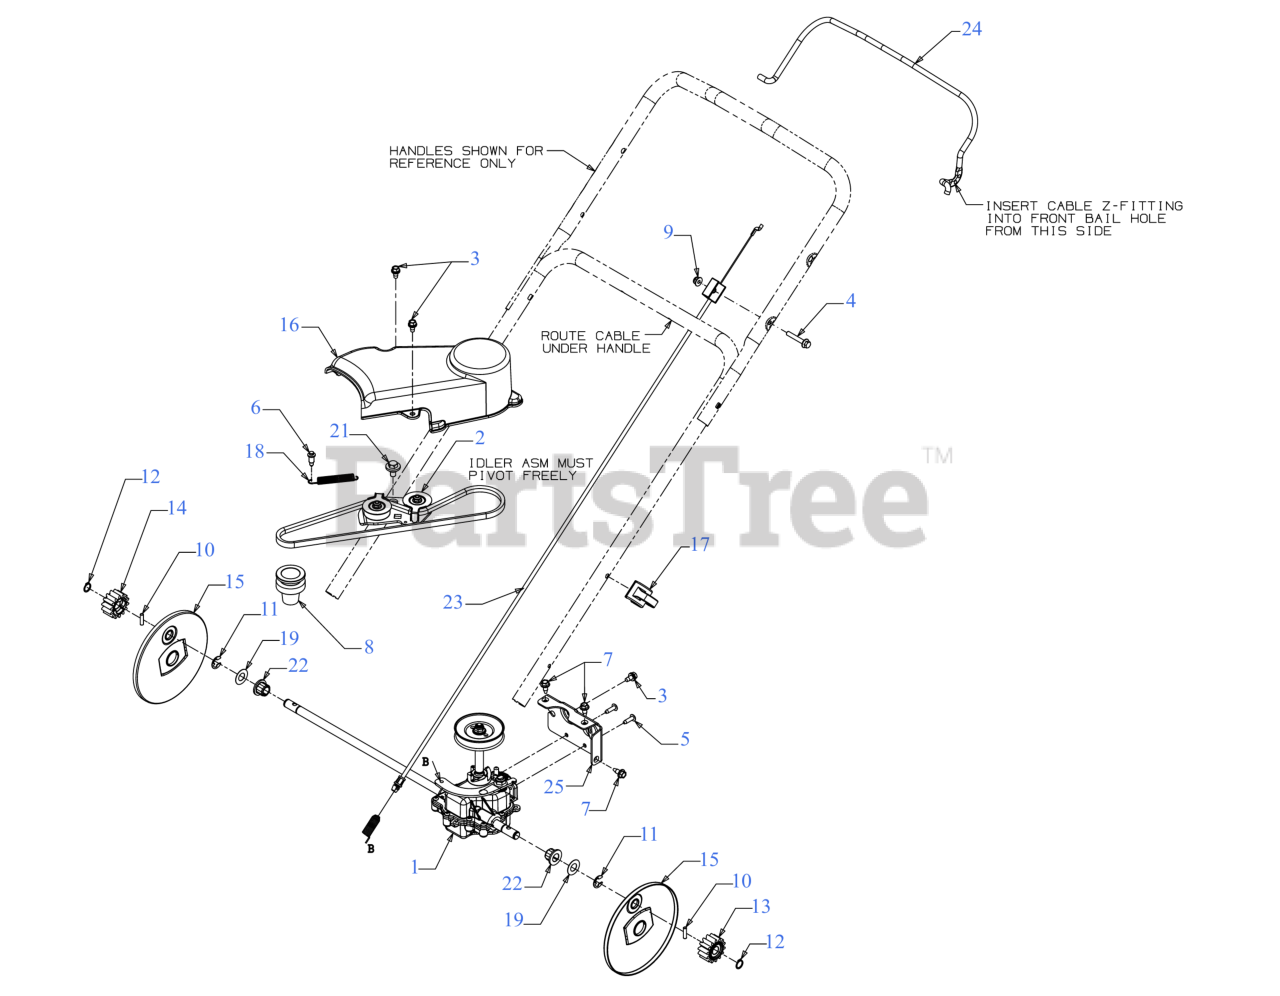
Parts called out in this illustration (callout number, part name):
1	TRANSMISSION
2	IDLER ASSEMBLY (COMPONENTS)
3	SCREW 1/4-20 x .50
4	SCREW 1/4-20 x 1.50 GR5
5	SCREW #12-16 x .750
6	SCREW .30 x .46
7	SCREW 1/4-20X.625
8	IMPELLER INSERT HUB
9	FLANGE LOCK NUT
10	DOWEL PIN
11	E-RING FOR .500 SHAFT
12	SNAP RING FOR .500
13	SPUR GEAR 14T (LH)
14	SPUR GEAR 14T (RH)
15	DUST WHEEL COVER
16	BELT COVER
17	CABLE GUIDE
18	EXTENSION SPRING
19	FLAT WASHER
21	SHOULDER SCREW .560X.165: 5/16-18
22	HEX FLANGE BEARING .506ID x .590LG
23	CONTROL CABLE
24	GULLWING DRIVE BAIL- YELLOW
25	MOUNTING BRACKET
